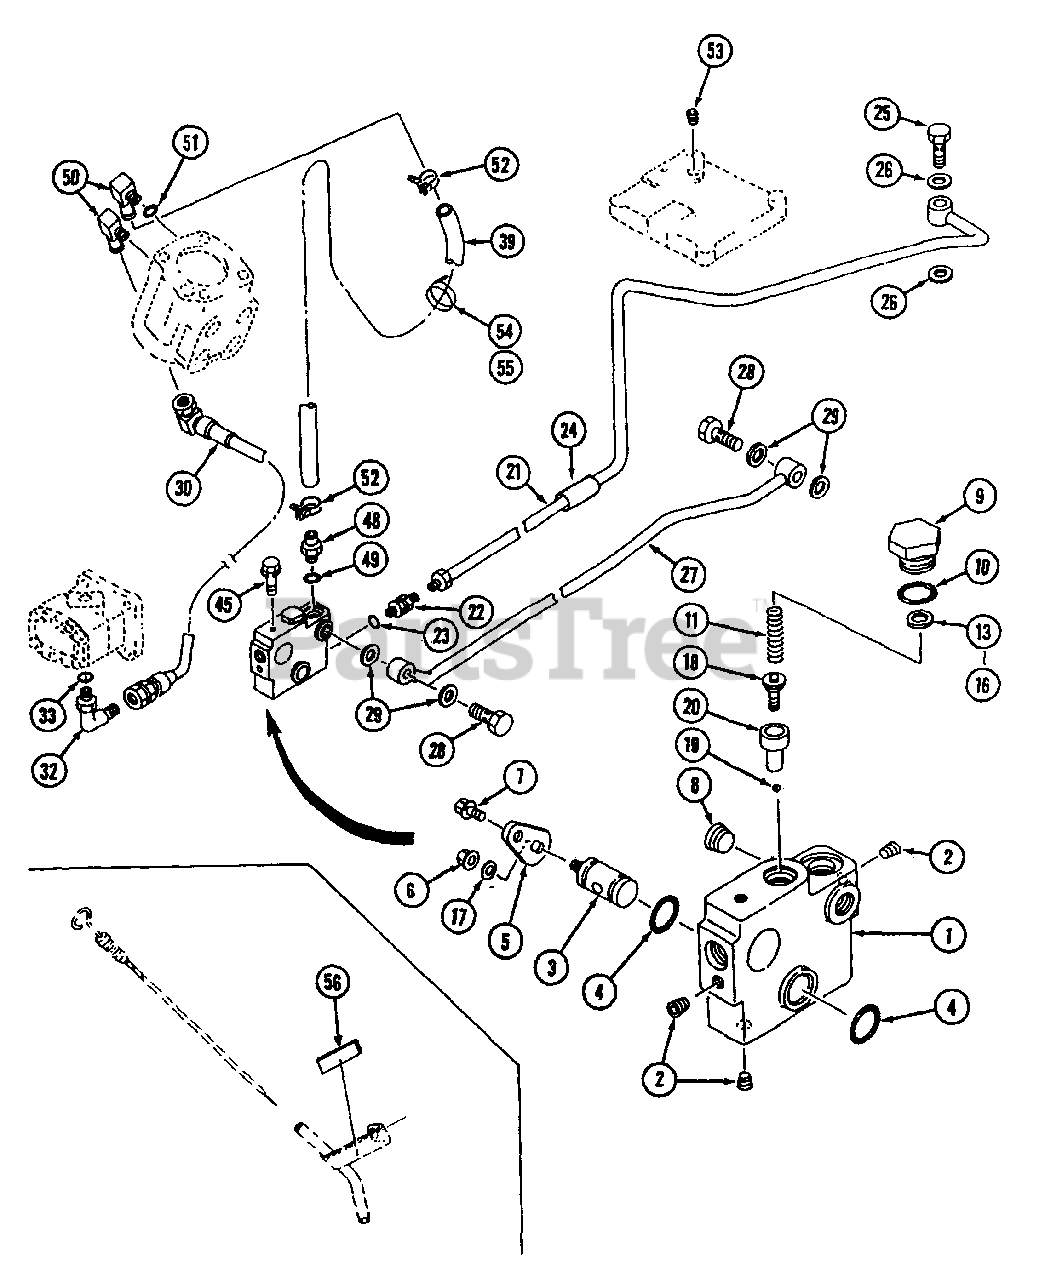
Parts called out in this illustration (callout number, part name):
19	Ball
20	Relief Housing (NLA)
21	Pipe C, Press Ass'y.
22	Body, (Nipple)
26	Seal Washer
27	Pipe D
29	Seal Washer
32	Adapter
39	Hose
48	Adapter
50	Elbow 90°
54	Band, Wire
56	Rubber
